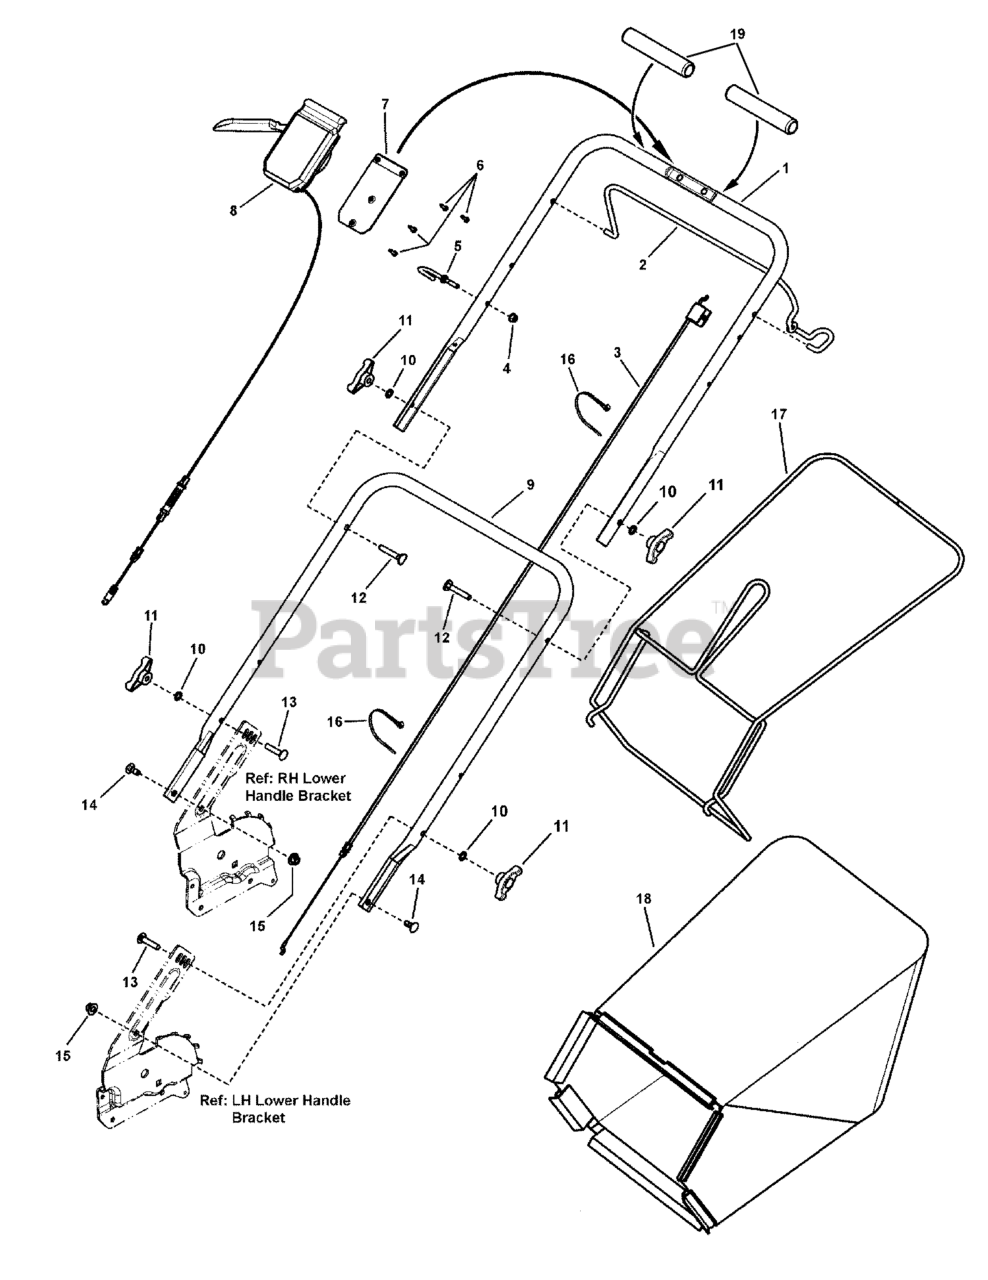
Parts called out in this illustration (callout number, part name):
1	HANDLE, Upper, Brute, Propelled
2	BAIL, Operator Presence Control, Propelled, Brute
3	CABLE, Bail, 22" WBM
4	NUT, 1/4-20 Hex Flange Esna, YZ
5	ROPE GUIDE (1/4-20 thread)
6	SCREW, #8-16, Pan Head Torxplus Recessed, Twin Helix
7	PLATE, Control Panel
8	ASSEMBLY, Control Box, Variable Speed
9	HANDLE, Lower, 21" Rear Discharge
10	WASHER, 5/16" Internal Tooth lock
11	KNOB, 5/16-18, Wing, Black
12	BOLT, 5/16-18 x 2" Curved Head Square Neck, GR 2
13	BOLT, 5/16-18 x 1-1/2" Round Head Short Square Neck Carriage, GR 5
14	BOLT, 5/16-18 x 3/4" Round Head Short Square Neck Carriage, YZ
15	NUT, 5/16-18 Large Head Center Lock
16	WIRE TIE, 11 Inch Std Black Nylon
17	BAG FRAME, Rear Discharge
18	BAG, Grass, 22" Rear Discharge
19	FOAM GRIP
